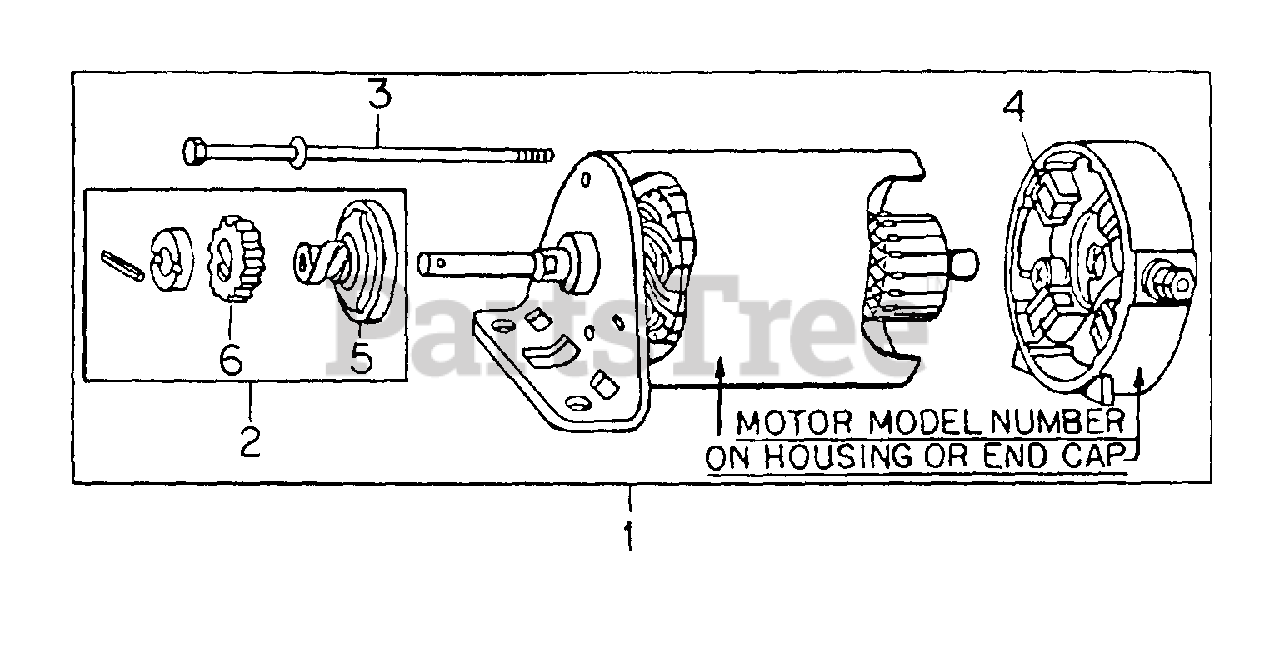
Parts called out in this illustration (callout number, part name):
1	MOTOR ASSY, STARTER
2	DRIVE
3	BOLT, 1/4-20 X 4 ZND HEX-HD MACH
4	BRUSH KIT
5	CLUTCH ASSY, STARTER
6	GEAR, STARTER DRIVE
